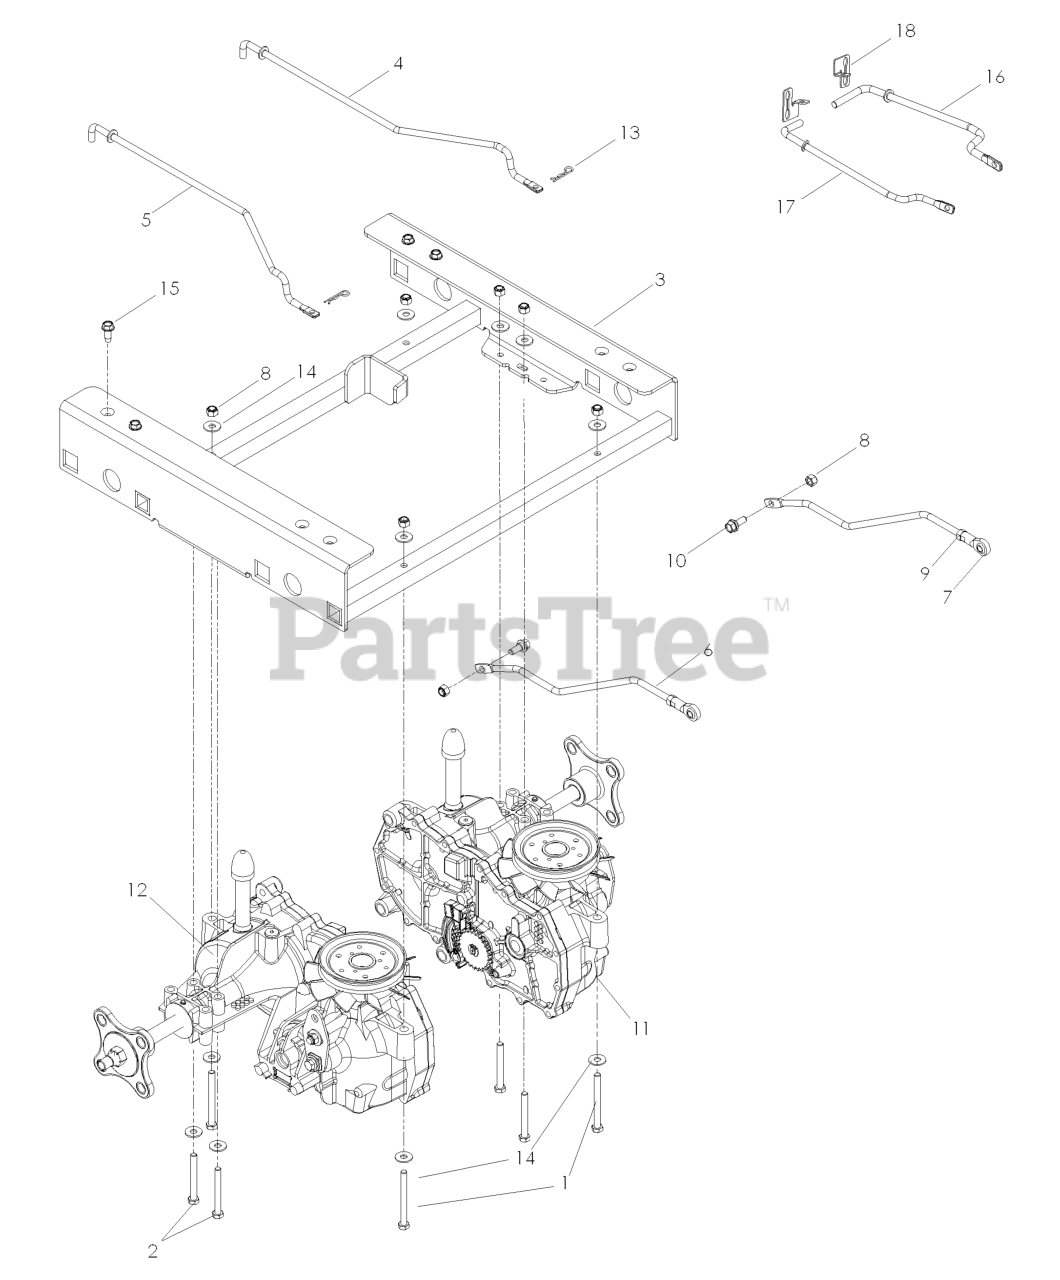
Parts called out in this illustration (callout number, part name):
1	HCS 5/16-18 X 3 1/4
2	HCS 5/16C X 2-3/4
3	SUB FRAME PAINTED
4	BYPASS LINKAGE, LEFT
5	BYPASS LINKAGE, RIGHT
6	MOTION CONTROL ROD ASM
7	BALL JOINT, RIGHT HANDED
8	NUT 5/16 NYLOC
10	BOLT, SHOULDER
11	HG_EZT, LT
12	HG_EZT RIGHT
13	HAIRPIN #2
14	WASHER 5/16 FLAT
16	LINKAGE, LEFT BYPASS
17	LINKAGE, RIGHT BYPASS
18	BRACKET, BYPASS - BLACK
